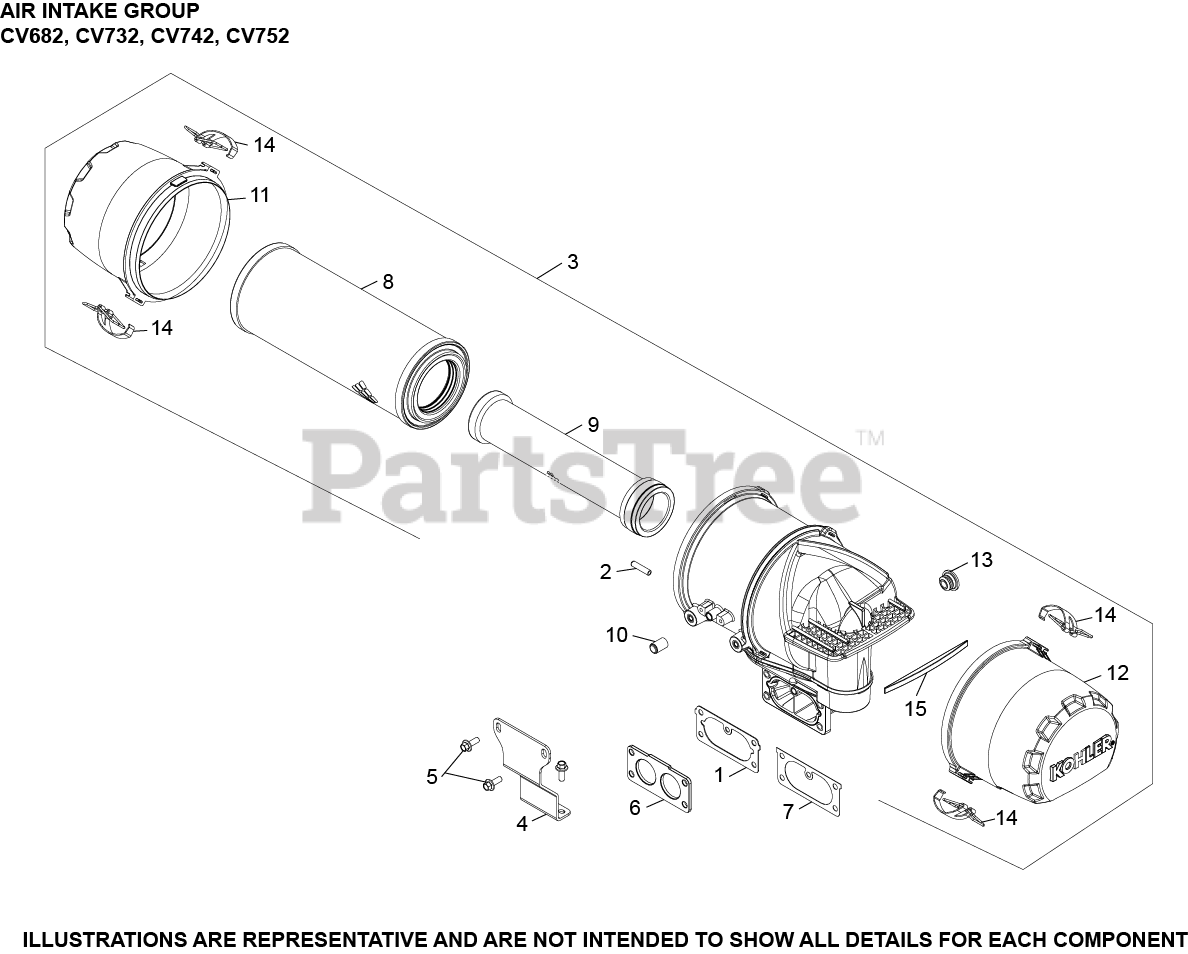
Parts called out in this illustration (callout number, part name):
1	GASKET, AIR CLEANER
2	CAP, MASKING
3	KIT, AIR CLEANER
4	BRACKET, SUPPORT
5	SCREW, FLG M6X1.0X16
8	ELEMENT, AIR FILTER - PRIMARY
9	ELEMENT, AIR FILTER - SAFETY
10	CAP, MASKING
11	COVER, AIR FILTER
12	COVER, RAIN CAP
13	PLUG, HOLE
14	CLIP ASSEMBLY
15	DAMPER, FOAM INSERT
